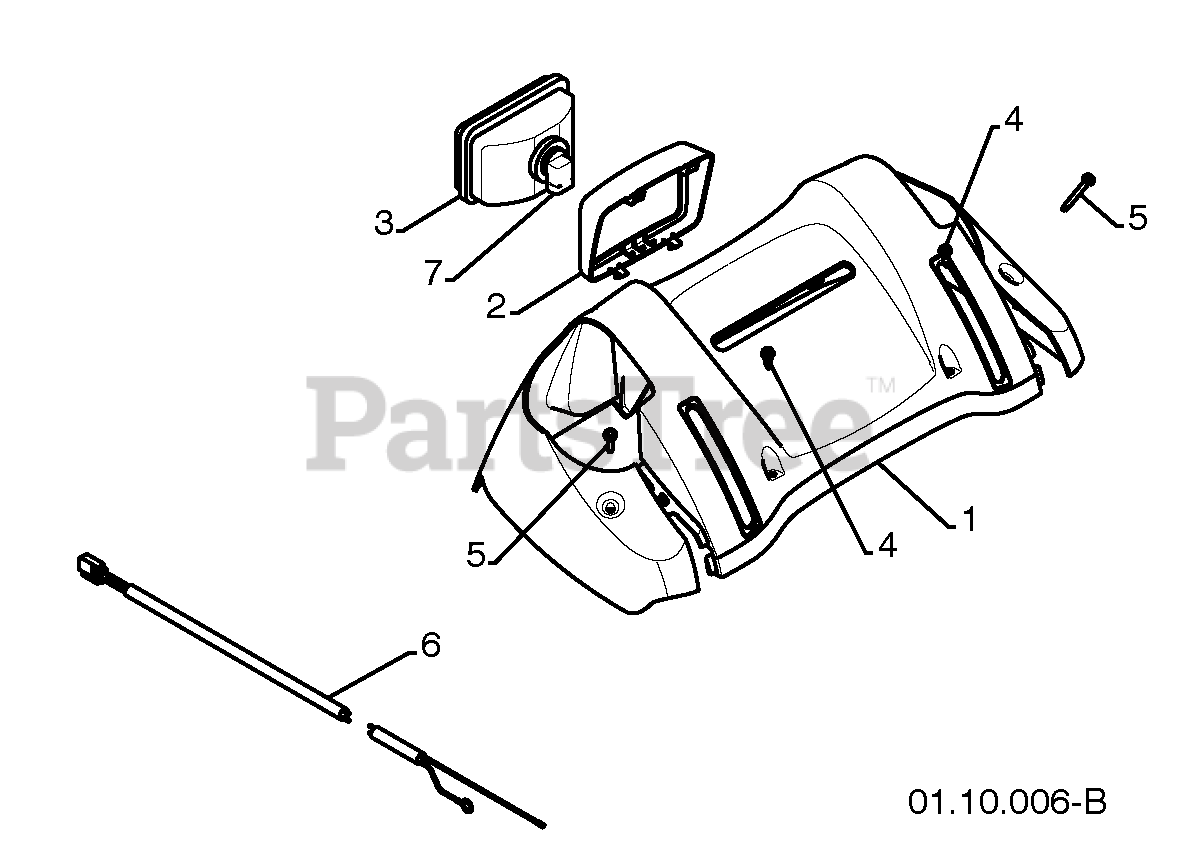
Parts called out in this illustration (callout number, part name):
1	PANEL CONSOLE
2	HEADLIGHT BEZEL
3	HALOGEN HEADLIGHT
4	SHOULDER SCREW
5	SCREW 10-24 X 1.25
6	WIRE HARNESS
7	BULB
